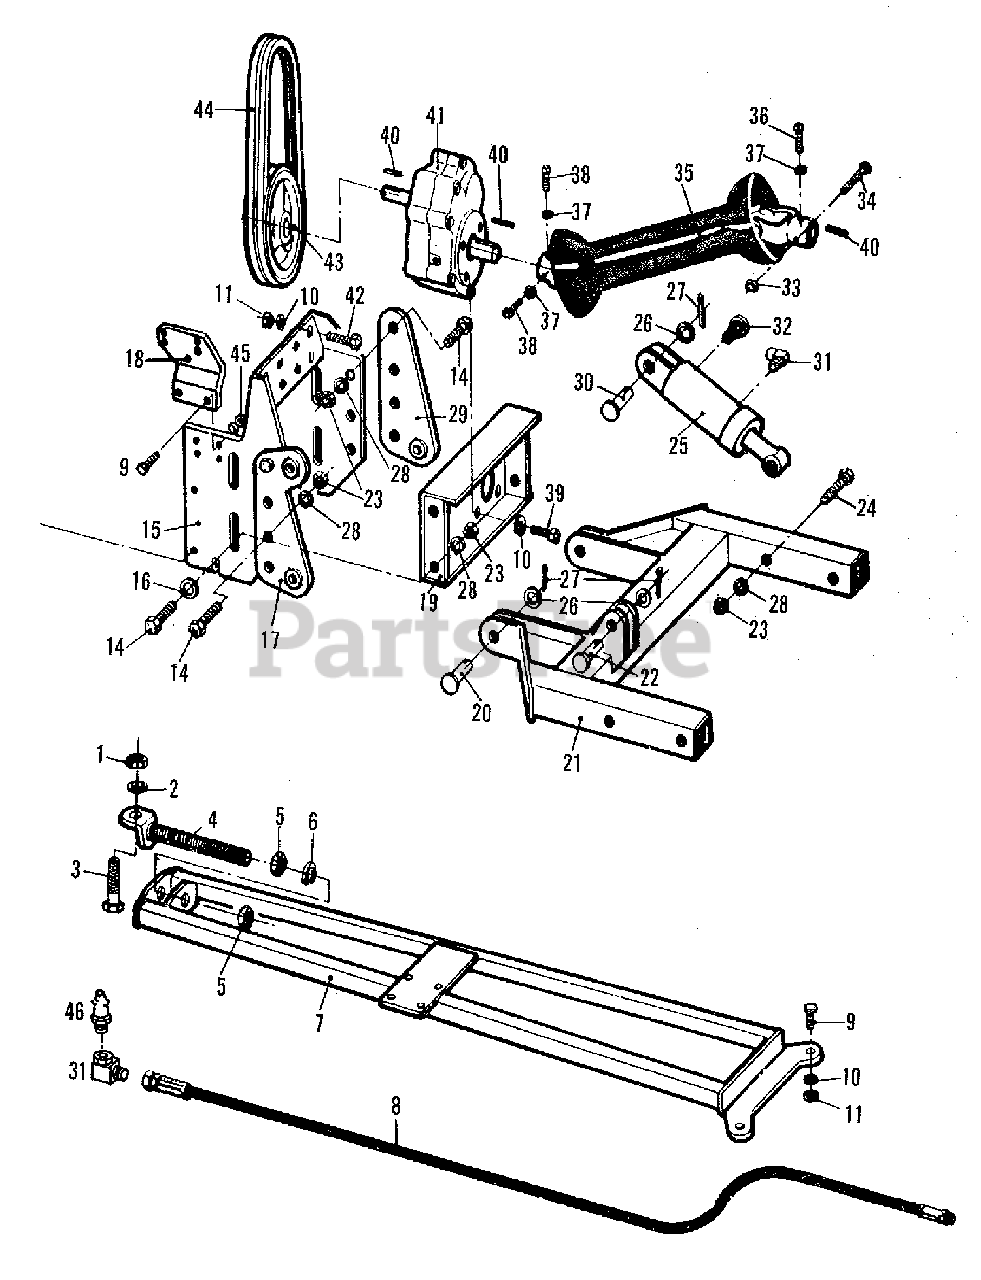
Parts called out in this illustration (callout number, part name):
2	LOCKWASHER, 3/4
3	CAPSCREW, 3/4NC x 3
4	BOLT, Adjuster
5	NUT, Jam, 1" NC
6	LOCKWASHER, 1"
7	FRAME, Under
8	HOSE ASSEMBLY (105")
8	COUPLER, Hydraulic - Tractor (Use w/Quick Disconnect Coupler)
9	CAPSCREW, 1/2NC x 1-1/2
10	LOCKWASHER, 1/2
12	CAPSCREW 3/8NC x 1
13	LOCKWASHER, 3/8
14	CAPSCREW, 5/8NC x 2
15	FRAME, Mounting
16	WASHER, 5/8
17	BRACKET, Hanger, Cylinder
18	BRACKET SET, Spacer (5030)
18	BRACKET SET, Spacer (5020)
19	FRAME, Gearbox
20	PIN, Frame, 5/8 x 2
21	FRAME, Front
22	PIN, Cylinder, 5/8 x 2-1/2
24	CAPSCREW, 5/8NC x 4
25	CYLINDER ASSEMBLY, Hydraulic, 2 x 4
26	WASHER, 5/8" I.D. x 1/16" Thick
27	PIN, Cotter, 1/8 x 1-1/2
28	LOCKWASHER, 5/8
29	HANGER, Bracket
30	PIN, Cylinder, 5/8 x 2-1/4
31	ELBOW, Steet, 3/8NPT
32	BREATHER ASSEMBLY, 3/8NPT
33	LOCKNUT, 5/16NC
34	CAPSCREW, 5/16NC x 3
35	SHAFT ASSEMBLY, PTO, Complete
36	SETSCREW, 3/8NC x 1
38	SETSCREW, 3/8NC x 1
39	CAPSCREW, 1/2NC x 1
40	KEY, 1/4 x 1/4 x 1-1/2
41	GEAR ASSEMBLY, Parallel Shaft (3.6:1 Ratio)
42	CAPSCREW, 1/2NC x 2
43	SHEAVE, F.H.P.
43	BUSHING, 1" Bore
45	NUT, Hex, Jam, Heavy, 1/2NC (Use w/SPACER)
